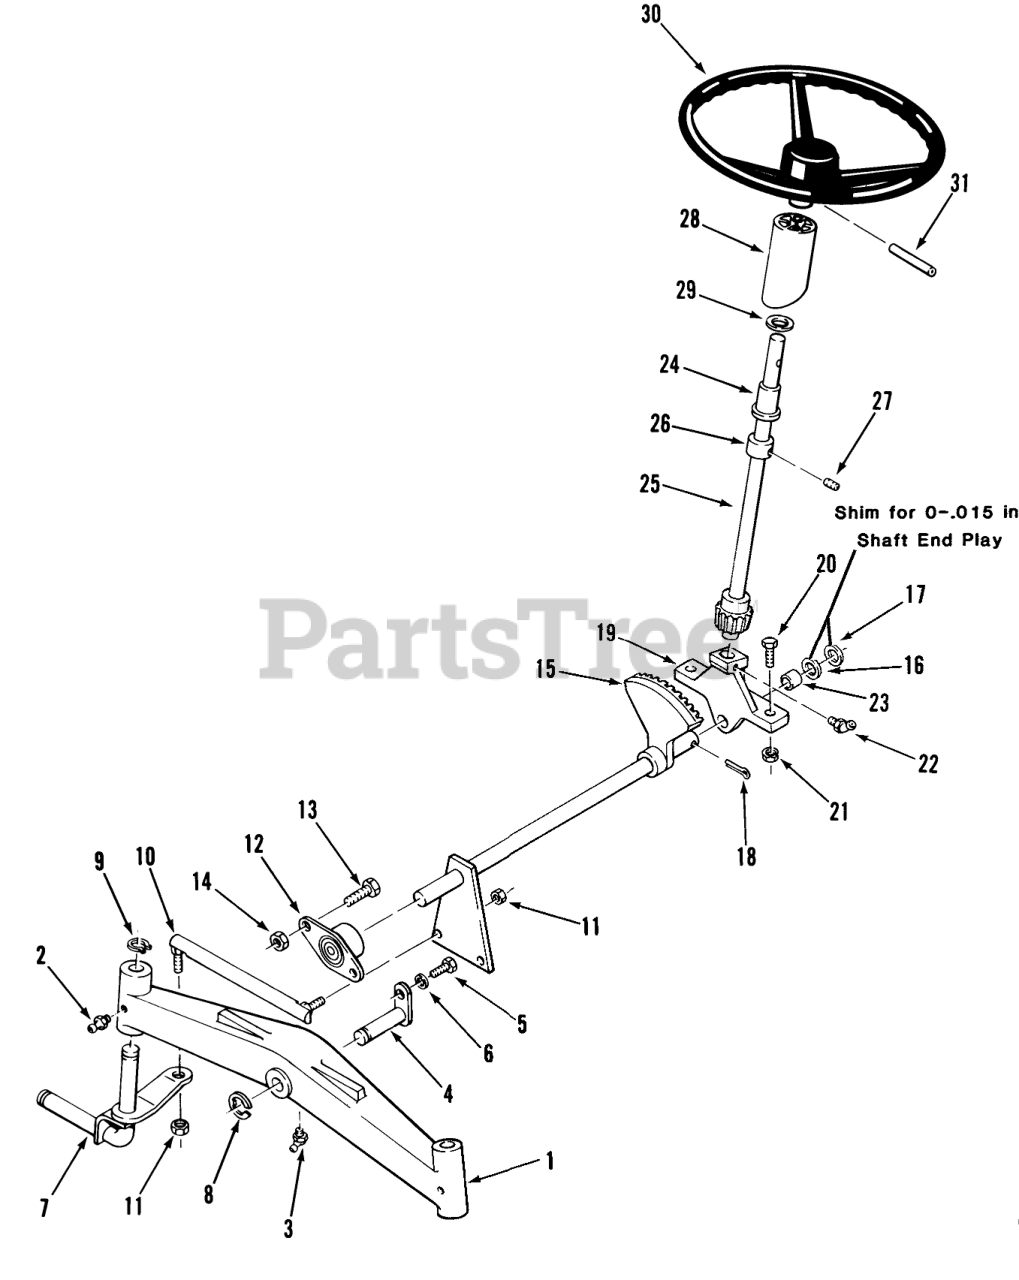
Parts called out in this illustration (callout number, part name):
1	AXLE-FRONT
2	Zerk
3	FITTING-GREASE
4	PIN AND PLATE ASM
5	H H C S
6	Lockwasher
7	Front Spindle RH
7	Front Spindle LH
8	E-RING
9	Snap Ring
10	Tie Rod RH
10	Tie Rod LH
11	NUT-6
12	BEARING-FLANGED
13	Bolt
14	Nut
15	Assy-Steering
16	WASHER-SHIM
17	WASHER
18	PIN-4
19	Support
20	BOLT
21	Nut
22	FITTING-GREASE
23	BEARING-BRONZE
24	BEARING-FLANGED
25	Shaft-Upper Steering
26	Collar
27	SCREW-SET
28	Collar
29	WASHER-BOWED
30	STEERING WH 13" PLAS
31	Pin-Roll
